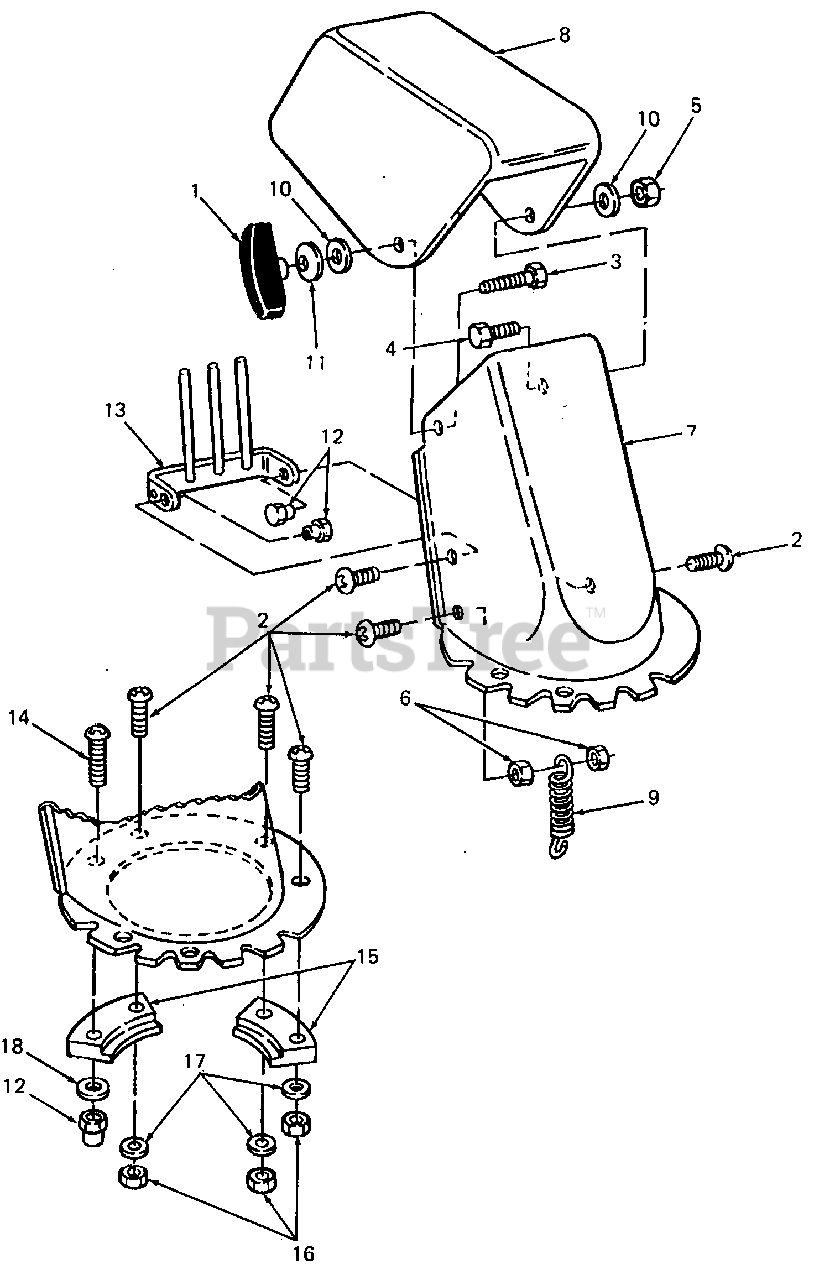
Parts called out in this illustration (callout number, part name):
1	Knob, Handle
2	Screw, Truss Mach, 1/4-20 X .75 Lg
3	Bolt, Carriage, 5/16-18 X 1.0 Lg
4	Screw, Truss Mach, 5/16-18 X .75 Lg
5	Nut, Hex Center Lock, 5/16-18
6	Nut, Hex Center Lock, 1/4-20
7	Chute, Lower, 6" Dia
8	Chute, Upper, 6" Dia
9	Spring, Extension, .36 OD X 2.5 Lg
10	Washer, Flat, .344 X 1.125 X .125 Thk
11	Washer, Bell, .345 X .88 X .060 Thk
12	Nut, Shoulder, 1/4-20
14	Screw, Truss Mach, 1/4-20 X 1.0 Lg
15	Keeper, Chute Flange
16	Nut, Hex Patch Lock, 1/4-20
17	Washer, Flat, .281 X .50 X .063 Thk
18	Washer, Flat, .265 X .93 X .120 Thk
